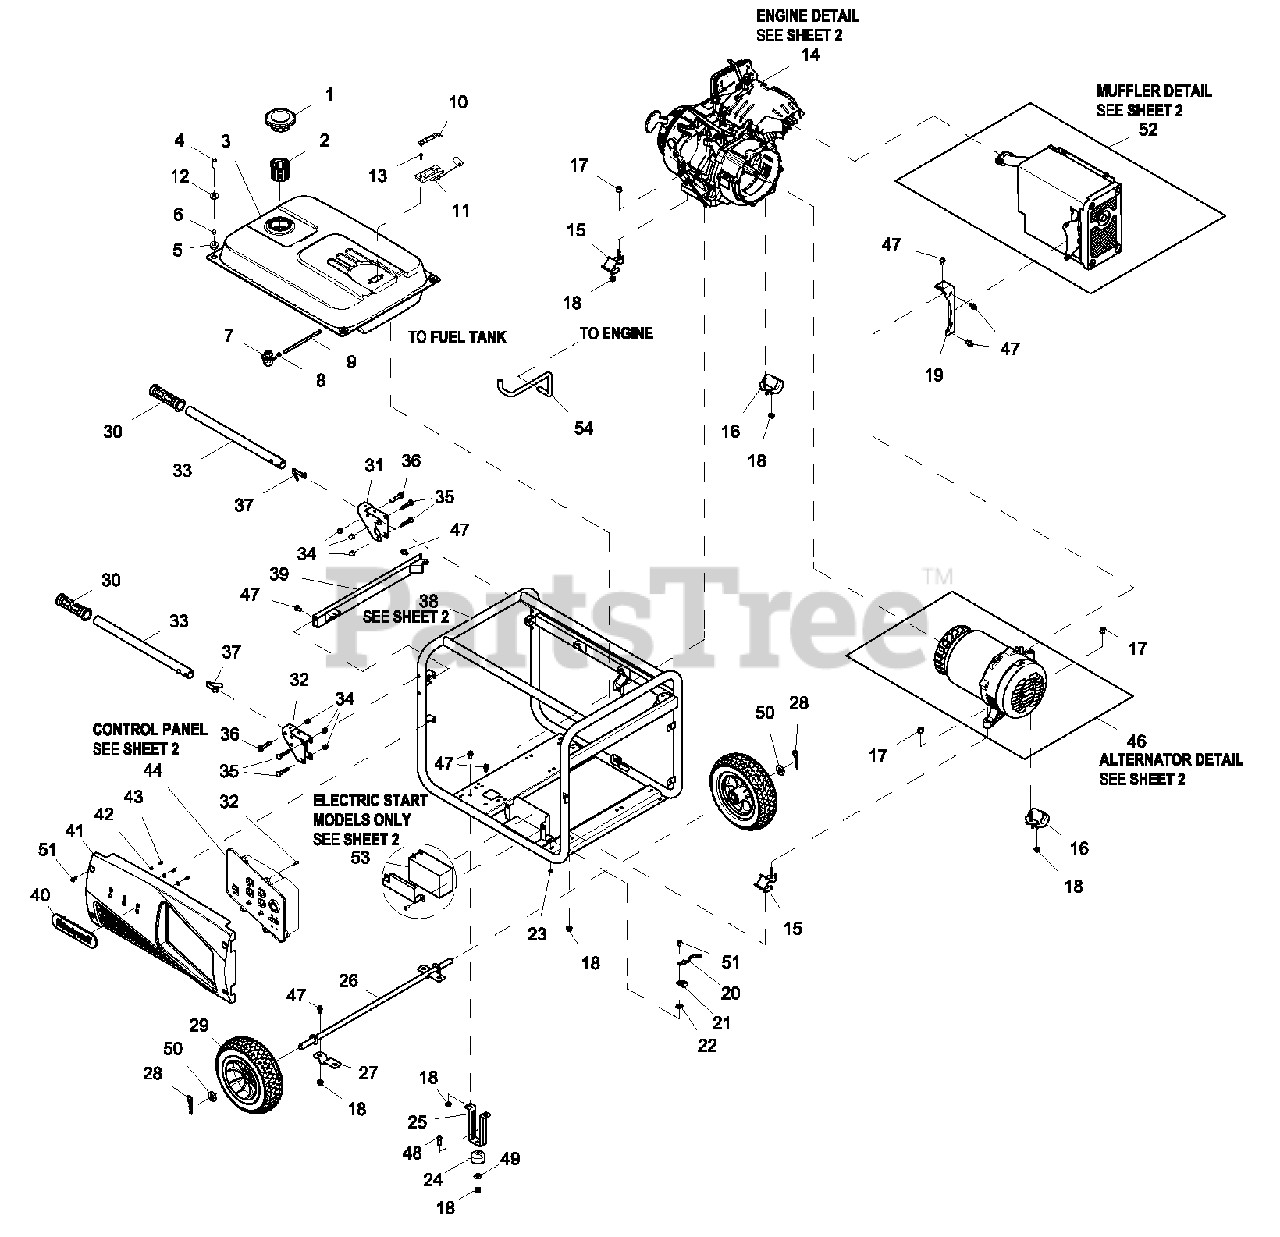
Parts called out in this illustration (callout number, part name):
1	FUEL CAP,NOT VENTED,BLACK CAP
2	FILTER, FUEL
3	FUEL TANK 5.8 GAL HNYWL EVAP
4	SCREW HHFC M6-1.0 X 25 FTH
5	RUBBER MOUNT,10.3 ID X11 HGT
6	INSERT, ANTI-CRUSH FOR TANKS
7	VALVE FUELSHUTOFF
8	CLAMP HOSE BAND SPRING .38
9	FUEL HOSE 4 ID X 8.50D X165MM
10	PLATE, FUEL GAGE
11	FUEL GAGE, 90MM LONG ARM
12	WASHER FLAT .266ID X 1.00D
13	SCREW PFHM M5-0.8X12
14	ENGINE HNYWL
15	VIB MNT 45DEG M8X13.5/M10X37.5
16	VIB MNT 45DEG M8X15.5/M10X37.5
17	NUT HEX FL WHIZ M10-1.25
18	NUT HEX FL WHIZ M8-1.25
19	BRACKET, MUFFLER 389CC
20	GND WIRE PORT BRG CARR-FRAME
21	LUG GROUNDING HONEYWELL
22	WASHER LOCK SPECIAL 1/4"
23	NUT HEX M6-1.0 G8 CLEAR ZINC
24	RUBBER FOOT
25	BENT FOOT HONEYWELL
26	WELDMENT AXLE AND BRACKET HW
27	AXLE BRACKET HONEYWELL
28	COTTER HAIRPIN 2.56 X.80
29	WHEEL 10.25" OD 5/8" AXLE
30	GRIP HANDLE HONEYWELL
31	BRACKET HANDLE LH HW PORT
32	BRACKET HANDLE RH HW PORT
33	HANDLE, HW PORTABLE
34	CAP NUT M8-1.25 BLACK ZINC
35	CHB M8-1.25X40MM LONG
36	SCREW,HHFC M8-1.25 X 45
37	SNAP BUTTON - .437" DIA. HEAD
38	CRADLE WELDMENT HNYWL
39	WELDMENT END RAIL HONEYWELL
40	BADGE, HW SIDE PANEL
41	PANEL, PLASTIC SIDE C-PNL PORT
42	WASHER FLAT #8 ZINC
43	SCREW PPPH #8-16 X 0.40" BZC
44	CONTROL PANEL HONEYWELL
45	SCREW PPPH #8-16 X .66" BZC
46	ASSY ALTERNATOR
47	SCREW HHFC M8-1.25 X14 W/M10
48	SCREW HHFC M8-1.25 X 25 W/M10
49	WSHR FLAT 22.60D X 8.6ID X3
50	WASHER FLAT 5/8 ZINC
51	SCREW HHFC M6-1.0X 14
52	MUFFLER HNYWL
53	BATTERY 12V10AH SEALED
54	EVAPORATIVE HOSE HONEYWELL
